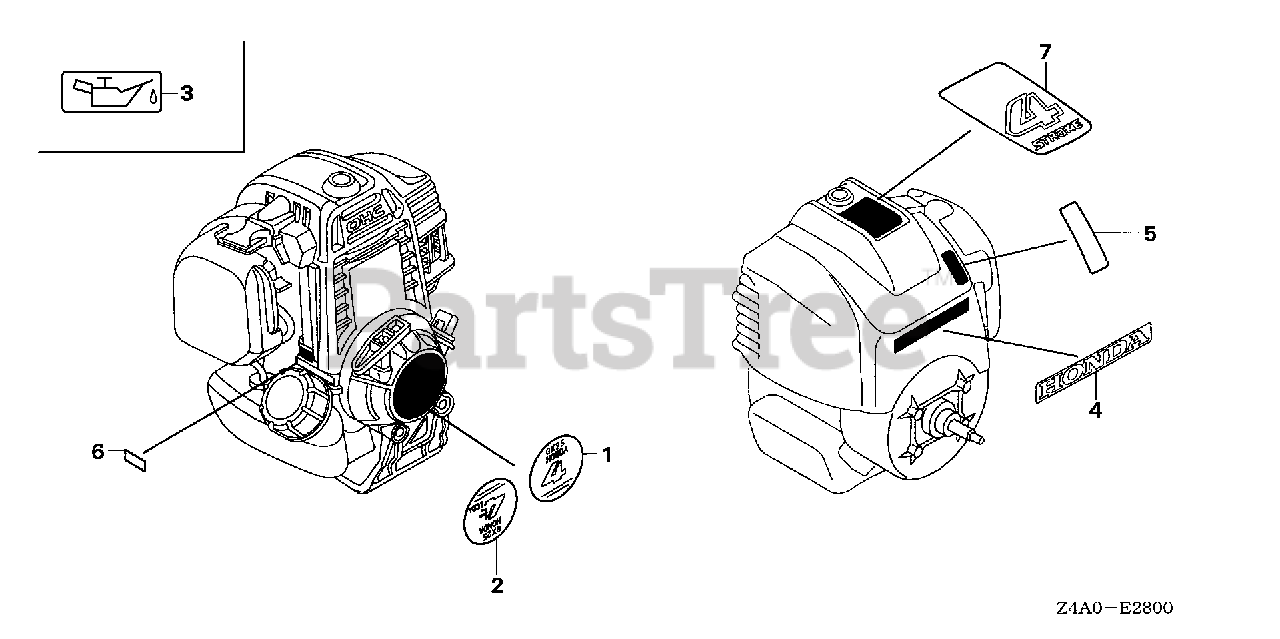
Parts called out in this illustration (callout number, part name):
1	MARK, EMBLEM
3	MARK, OIL CAUTION
6	MARK, TYPE (T3)
